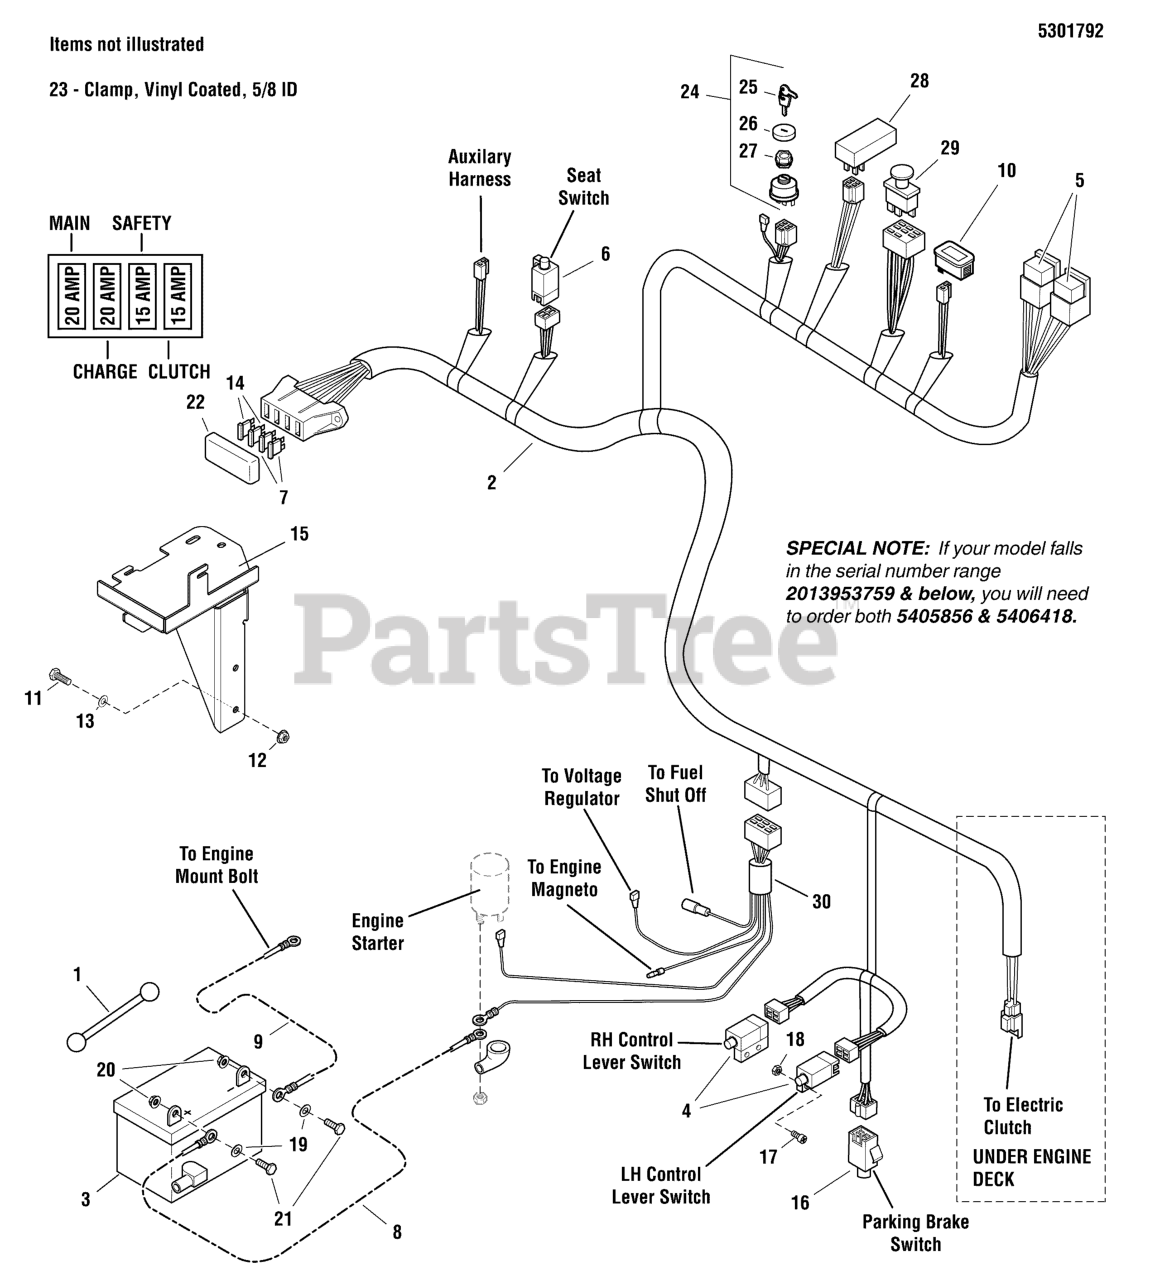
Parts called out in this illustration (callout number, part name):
1	STRAP-BLACK RUBB
2	WIRE HARNESS, MAIN, S75X
3	BATTERY, WET (BCIU1, 340 CCA)
4	SWITCH, PLUNGER, N.O.
5	RELAY, 12V, 40A
6	SWITCH, PLUNGER, NO/NO BOLT-ON
7	FUSE, ATO-15 (15 AMP)
8	BATTERY CABLE, POSITIVE, 30"
9	BATTERY CABLE, NEG, 22, 1/4-5/16
10	HOUR METER
11	BOLT, 3/8-16 X 1" GD5 CZ
12	NUT, 3/8-16 HEX NYLOCK FLANGE
13	WASHER, 3/8 SAE
14	FUSE, ATO, 20 AMP
15	WELD, BATTERY MOUNT - RED
16	SWITCH, DP NO/NC SNAP-IN
17	SCREW- #10-24 X 1/2 ROUND PHILLIPS
18	NUT, #10-24 HEX NYLON LOCK
19	WASHER, 1/4 SAE
20	NUT, 1/4-20 HEX NYLOCK FLANGE
21	BOLT, 1/4-20 X 3/4 GD5 YZ
24	SWITCH, IGNITION, 6 POST
25	KEY, IGNITION MOLDED SET
26	COVER, PLASTIC, SNAP ON
27	PLASTIC NUT
28	MODULE, TIME DELAY
29	SWITCH, BLADE ENGAGEMENT
30	WIRE HARNESS, JUMPER, S75X 26HP
